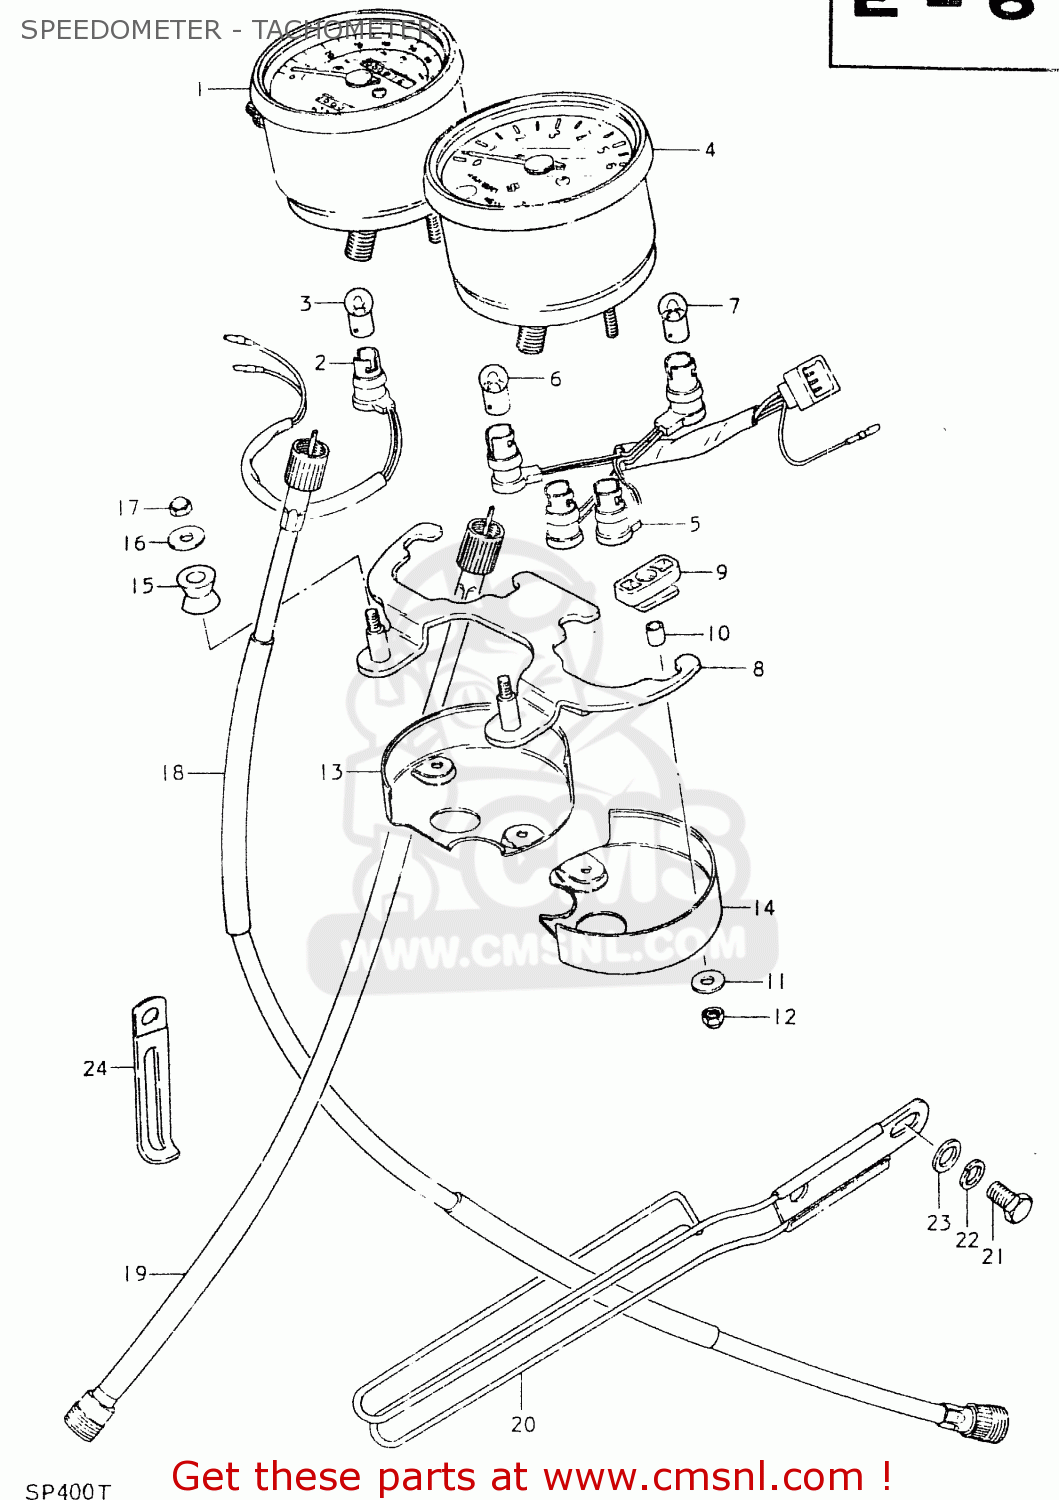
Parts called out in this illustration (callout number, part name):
1	SPEEDOMETER
2	SOCKET,METER
3	BULB(6V/3W)
4	TACHOMETER ASSY
5	SOCKET,TACHOMETER
6	BULB(6V1.7W,STANLEY,A61A)
7	BULB(6V/3W)
8	BRACKET,COMBINATION METER
9	CUSHION
10	SPACER
11	WASHER (5.5X16X1.2)
12	NUT
13	COVER,METER,UNDER
14	PLATE,TACHOMETER UNDER
15	CUSHION
16	WASHER
17	NUT
18	CABLE ASSY,SPEEDOMETER
19	CABLE ASSEMBLY,TACHOMETER
20	GUIDE,CABLE
21	BOLT 8X12
22	LOCK WASHER
23	WASHER
24	CLAMP L:35
